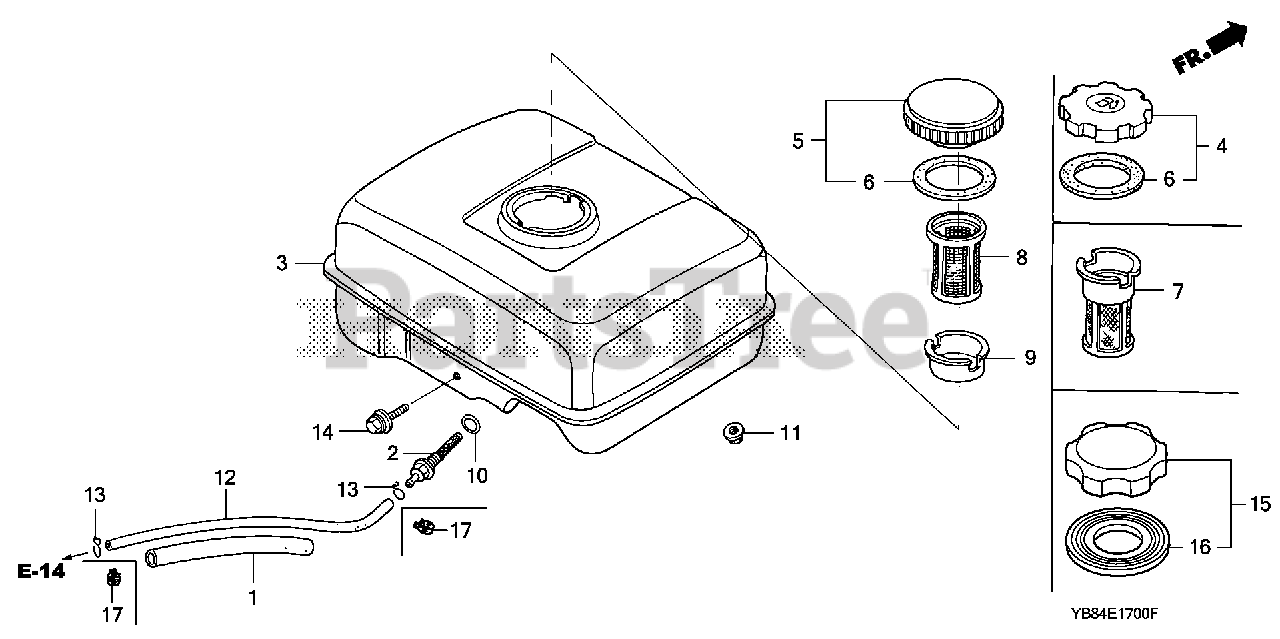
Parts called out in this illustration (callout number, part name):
1	RUBBER, SUPPORTER (107MM)
2	JOINT, FUEL TANK
3	TANK, FUEL *NH31* (MCKINLEY WHITE)
7	FILTER, FUEL
10	O-RING (13.5X1.5) (ARAI)
10	O-RING (14MM) (NOK)
11	NUT, FLANGE (6MM)
12	BULK HOSE, FUEL (4.5X3000) (4.5X140)
13	CLIP, TUBE (B8)
14	BOLT, FLANGE (6X29)
15	CAP, FUEL FILLER (CHROME PLATED)
16	GASKET, FUEL FILLER CAP (39X62X3) (TOUYOUSYA)
